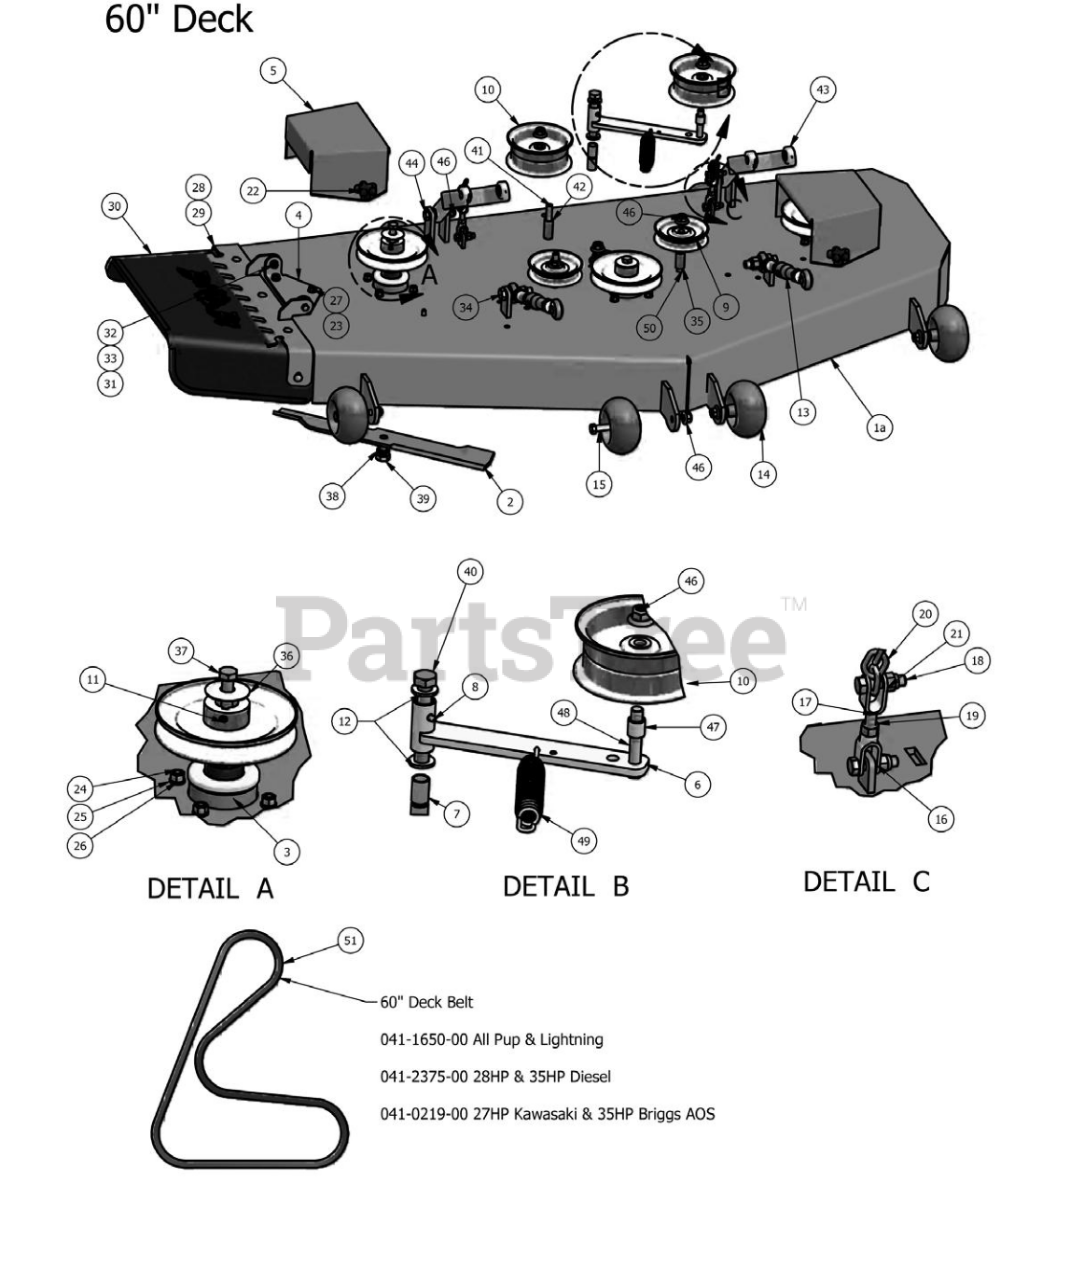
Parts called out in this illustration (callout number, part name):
1	60" Deck Complete Assembly with Spindles
2	60 Inch Fusion Blade
3	Double Bearing Spindle Assembly
4	Discharge Chute Hanger
5	Pulley Cover
6	Deck Idler 2009
7	5/8 x 1 1/8" Brass Bushing
8	1/4 Drive-in Grease Fitting
9	4 3/4" Idler Pulley
10	5 3/4" Deck Idler Pulley
11	6 1/4" Drive Pulley
12	.635 ID Plastic Washer
13	Turnbuckle (Top Link)
14	Anti-Scalp Rollers
15	1/2" x 4" Bolt (Grade 8)
16	Female Yoke
18	3/8" x 1 1/2" Hex Bolt
19	3/8" Hex Nut
20	4" Chain Assembly Lightning, AOS & Diesel
21	3/8 Nylock Nut
23	3/8" x 3/4" Hex Bolt
24	3/8" x 1 1/4" Hex Bolt
25	3/8" Lock Washer
26	3/8" Hex Nut
27	3/8" Flange Nut
28	60" Lower Hanger
29	60" Discharge Chute Upper Hanger Plate
30	Rubber Discharge Chute
31	.360 ID Plastic Washer
32	5/16" x 1" Hex Bolt
33	5/16" Nylock Flange Nut
34	5/8" x 2 1/2" Hex Bolt
35	Pup Pulley Spacer
36	Cup Washer
37	1/2" x 1 1/2" Hex Bolt
38	5/8" Lock Washer
39	5/8-18 x 1 1/2 GR 8 Hex Bolt
40	5/8" x 4" Hex Bolt
41	1/2-13 x 3 1/2 GR 5 Hex Bolt
42	1 3/4" Pulley Spacer
43	Deck Arm Assembly
44	1/2" x 2 1/2" Hex Bolt
45	1/2" Flange Nut
46	1/2-13 Nylon Flange Nut-Orange
47	3/4 OD x 1/2 ID x 3\4 Length
48	1/2 x 3" Bolt
49	Deck Idler Spring 2009
50	1/2 x 3 1/2 Flange Bolt Grade 8
51	Deck Belt All Pup & Lightning
